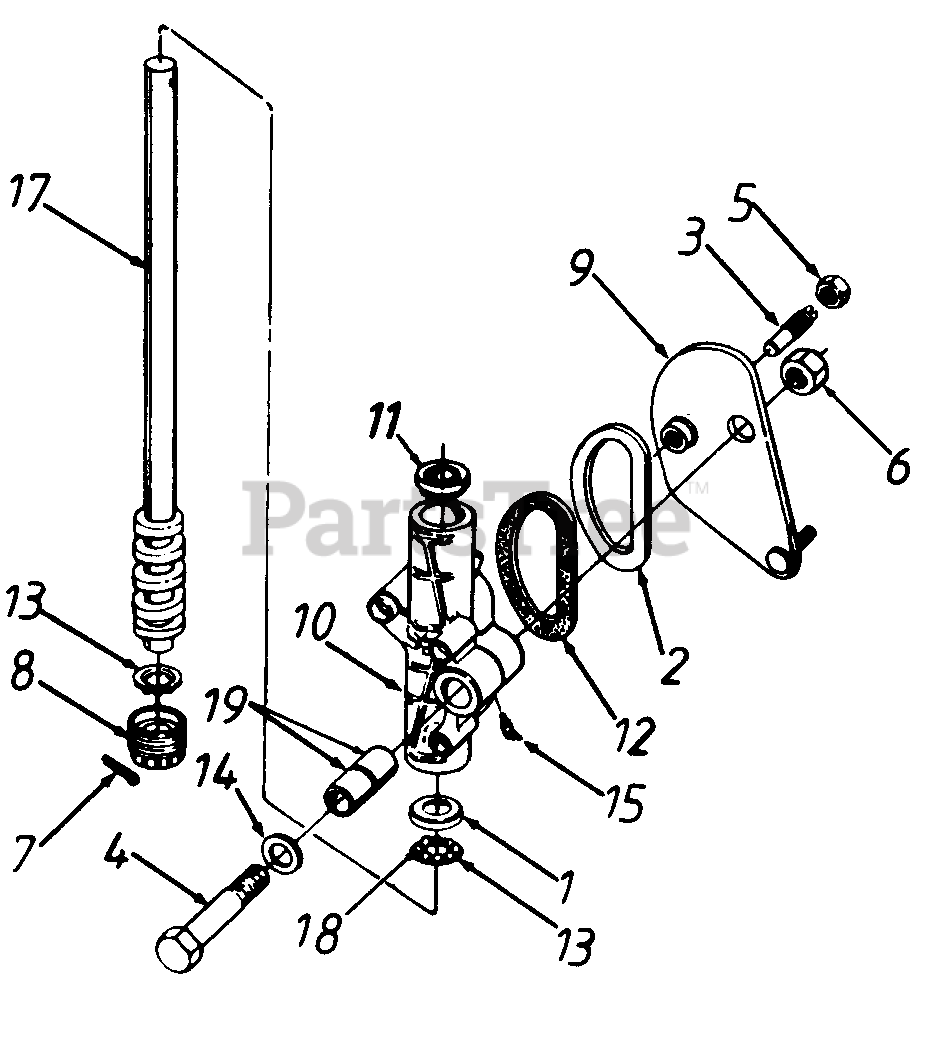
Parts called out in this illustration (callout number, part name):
1	Bearing Cup
2	Seal Retainer
3	Cam Follower
4	Pivot Shaft
5	Hex Jam Nut 9/16-18 Thd.
6	Hex Crown L-Nut 5/8-18 Thd.
7	Cotter Pin 1/8" Dia.
8	Adjustment Plug Ass'y.
9	Steering Arm Ass'y.
10	Steering Gear Hsg.
11	Oil Seal
12	Seal
13	Ball Retainer
14	Fl-Wash. .781" I.D. x 1.25" O.D.
15	Grease Fitting
17	Steering Shaft Ass'y.
18	Ball Bearing
19	Housing Bushing
